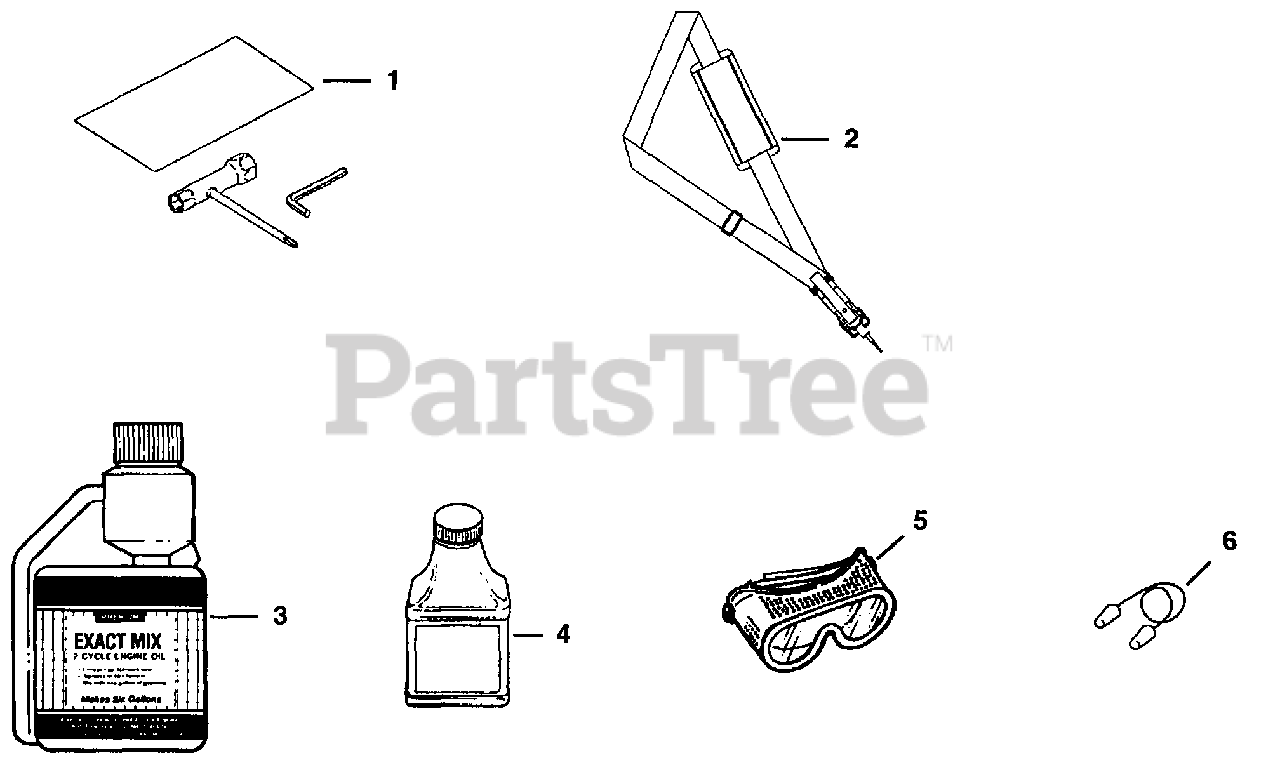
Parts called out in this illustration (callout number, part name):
1	TOOL KIT
3	EXACT MIX(TM) (16 oz.)
4	EXACT MIX(TM) (2.6 oz.)
6	EAR PLUGS
7	DECAL KIT
